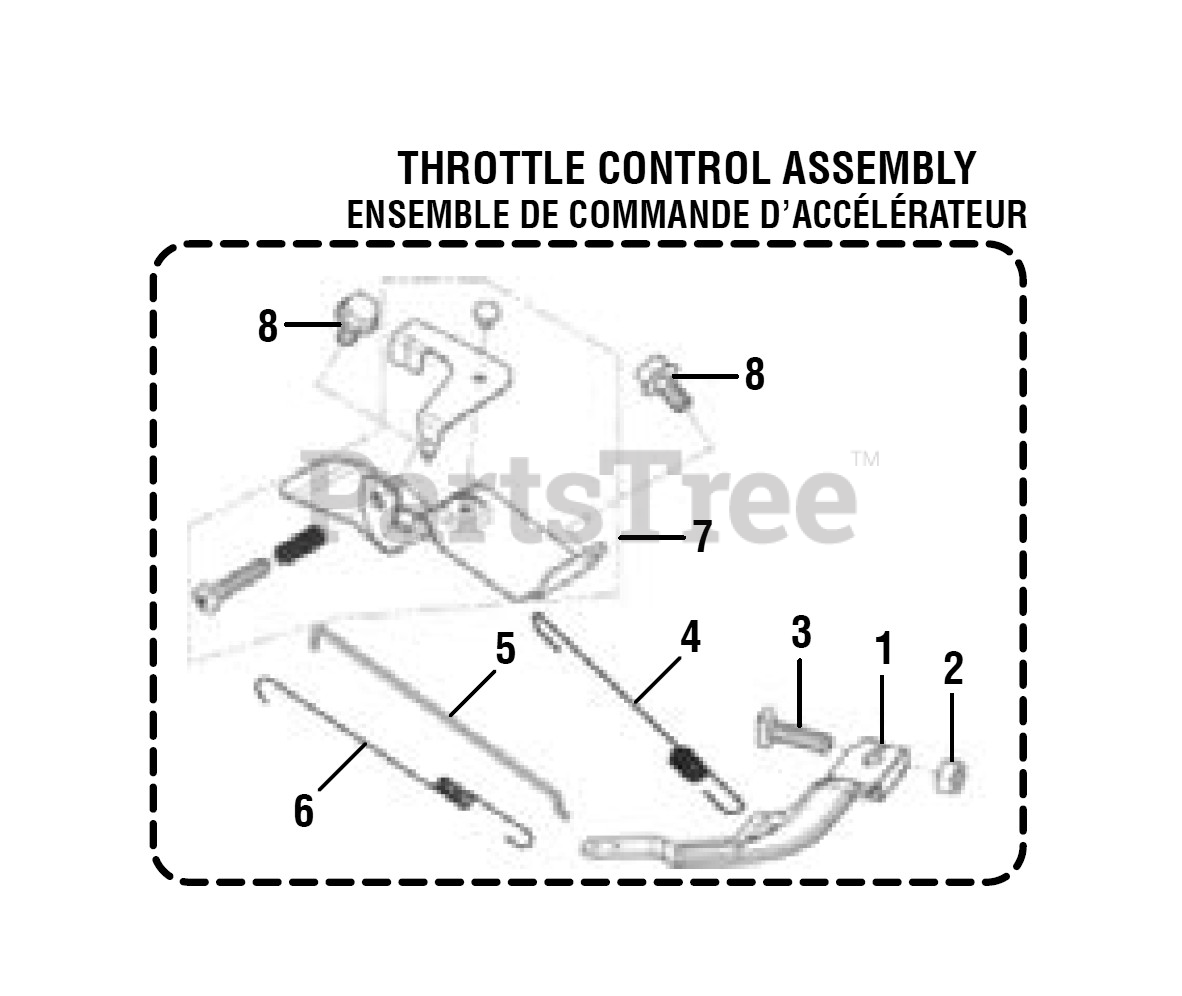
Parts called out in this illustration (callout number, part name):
1	Governor Support Assembly
3	Governor Support Bolt
4	Governor Spring
5	Governor Rod
6	Throttle Valve Return Spring
7	Throttle Control Assembly
